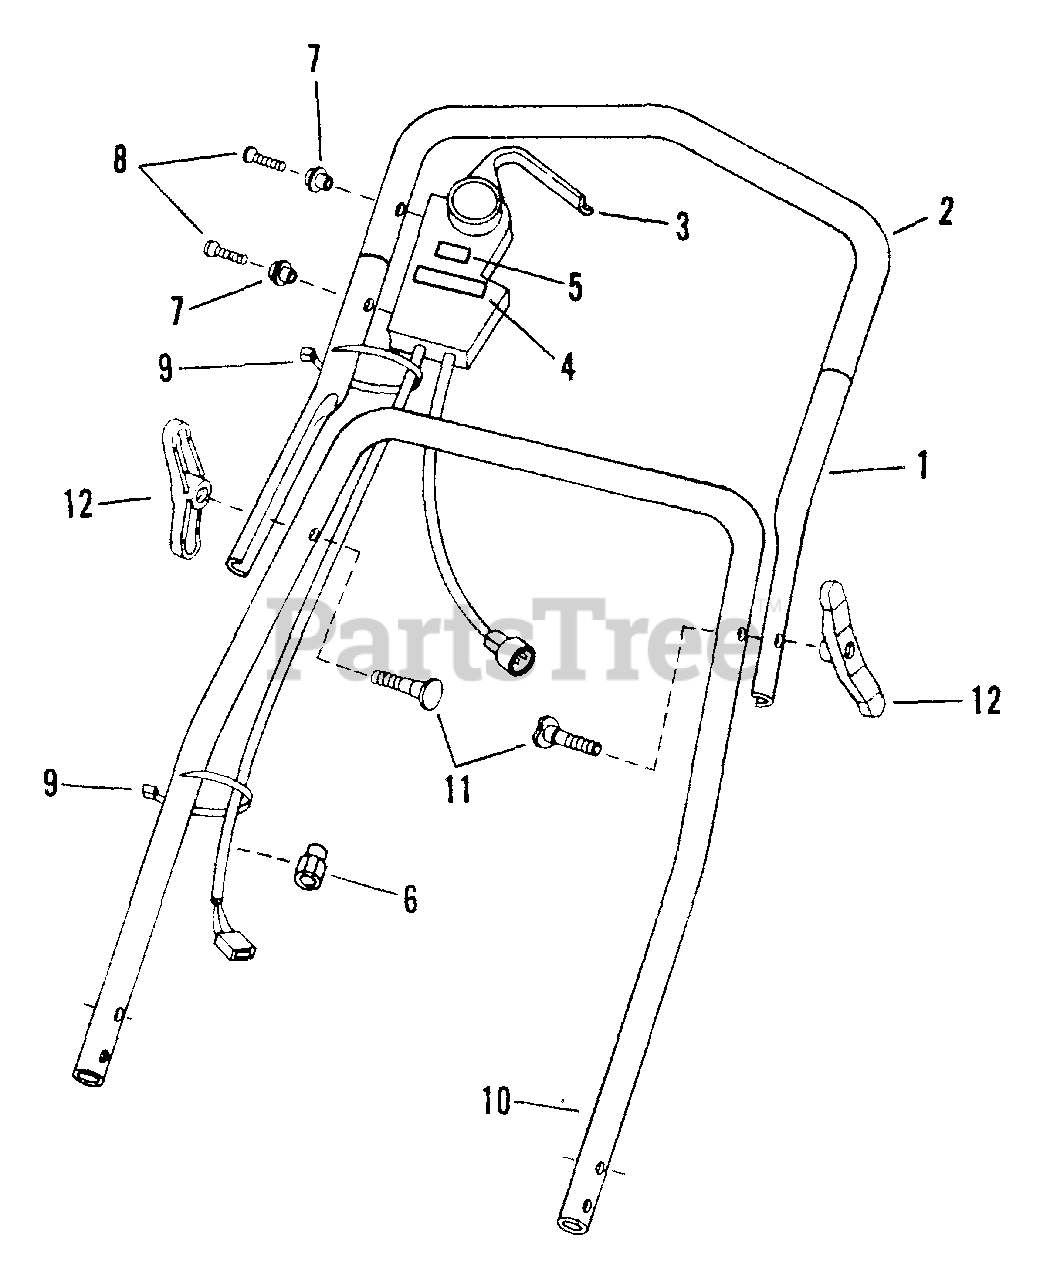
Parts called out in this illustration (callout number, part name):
1	ASSEMBLY Upper Handle
1	ASSEMBLY, Upper Handle
2	TUBING, Heat Shrink
3	CONTROL, Electric
4	DECAL, Starting Procedure
5	DECAL, Circuit Breaker Reset
6	STRAIN-RELIEF, Harness
7	INSULATOR, Handle
8	SCREW, #10-24 x 1-3/8" Slotted Cap
9	TIE, Cable
10	HANDLE, Middle
11	SCREW, 1/4-20 x 1-3/8" Curved Head
11	SCREW, 1/4-28 x 1-1/4" Hex Cap
12	NUT, 1/4-20 Wing
